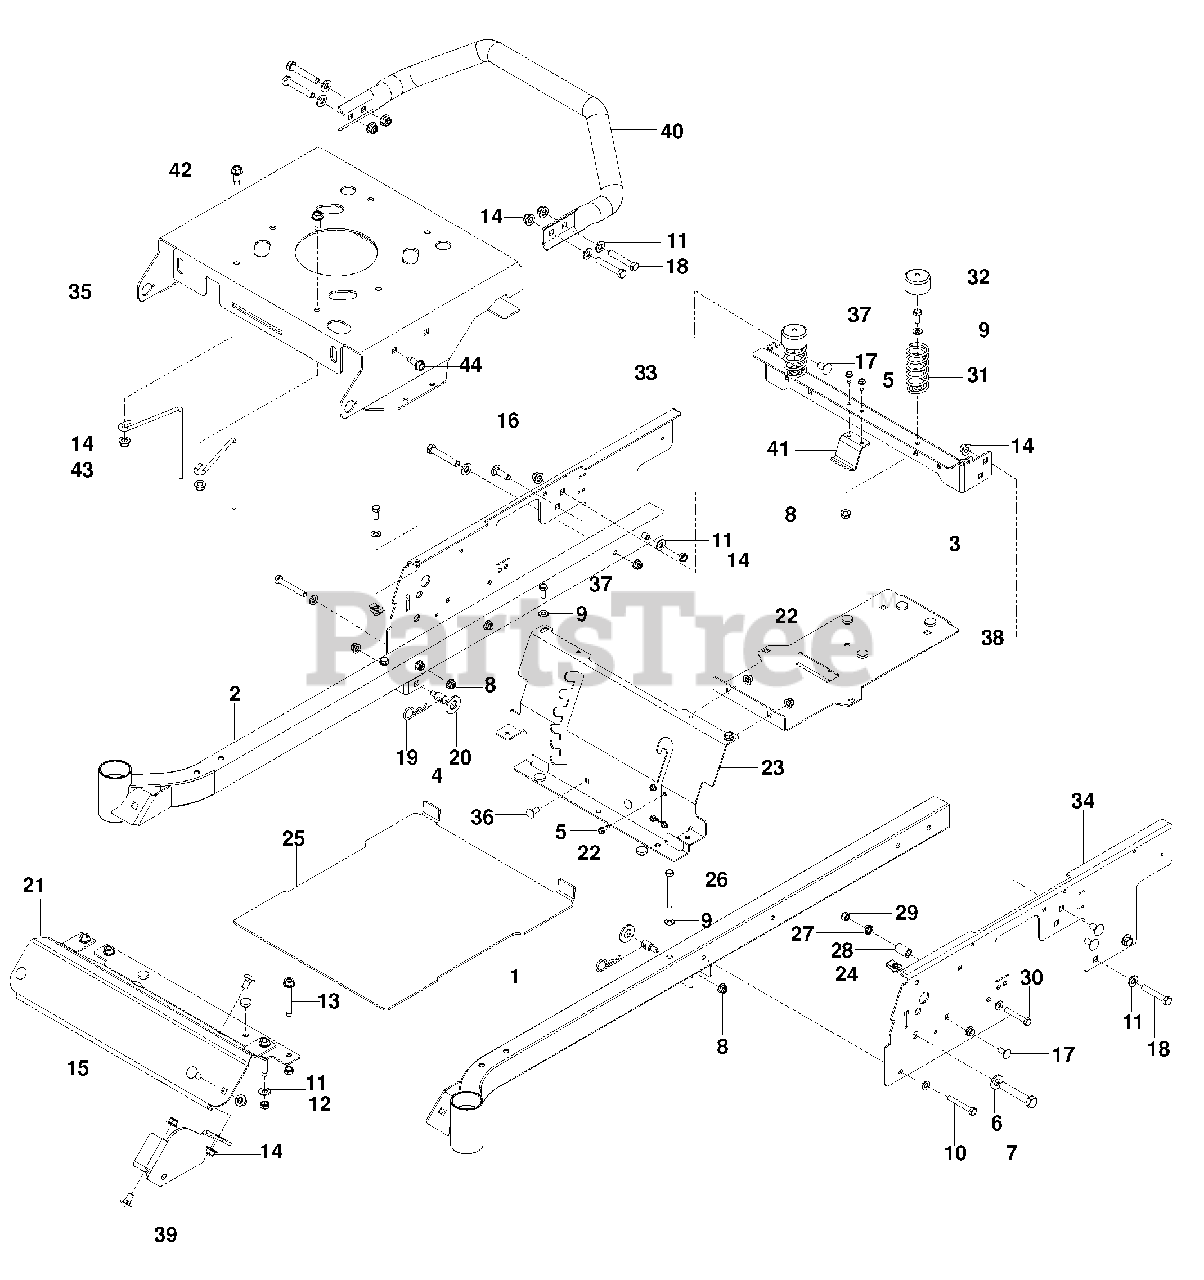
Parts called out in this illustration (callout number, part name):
1	FRAME TUBE, LH ORG
2	FRAME TUBE, RH ORG
3	SUPPORT, REAR SEAT ORG
4	STUD w/ ANTI-ROTATE
5	SCREW 1/4-20 x 5/8 SLF TAP
6	WASHER 1/2 SAE
7	HCS 1/2-13 x 2 3/4
8	NUT 5/16-18 FLANGE NYLOC
9	WASHER 5/16 SAE FLT
10	HCS 5/16-18 x 2 1/4
11	WASHER 3/8 SAE FLT
12	NUT 3/8-16 HEX JAM NYLOC
13	BOLT 3/8-16 x 25/8 THD FRM
14	NUT 3/8-16 FLANGE NYLOC
15	RHSNB 3/8-16 x 1
16	RHSNB 3/8-16 x 1 1/4
17	RHSNB 3/8-16 x 3/4
18	HCS 3/8-16 x 2 1/4
20	WASHER 5/8 SAE FLT
21	FOOT REST ORG
22	GROMMET,BUMPER
23	PANEL, SEAT SUPPORT ORG
24	U TYPE RETAINER
25	FOOT PLATE ORG
26	HCS 5/16-18 x 2 3/4
27	NUT 5/16-18 HEX WHIZLK
29	NUT 5/16-18 HEX NYLOC
30	HCS 5/16-18 x 2
31	SPRING, SEAT
32	CAP, SPRING
33	PLATE, RH ORG
34	PLATE, LH ORG
35	PLATE, ENGINE ORG
36	RHSNB 5/16-18 x 3/4
37	HCS 5/16-18 x 3/4
38	SUPPORT, TANK
39	BRACKET, FRONT DECK
40	GUARD, REAR ORG
41	BRACKET, FUEL TANK
42	BOLT 3/8-16 x 1 THD FRM
43	GUIDE, BELT
44	BOLT 5/16-18 x 1 THD FRM
